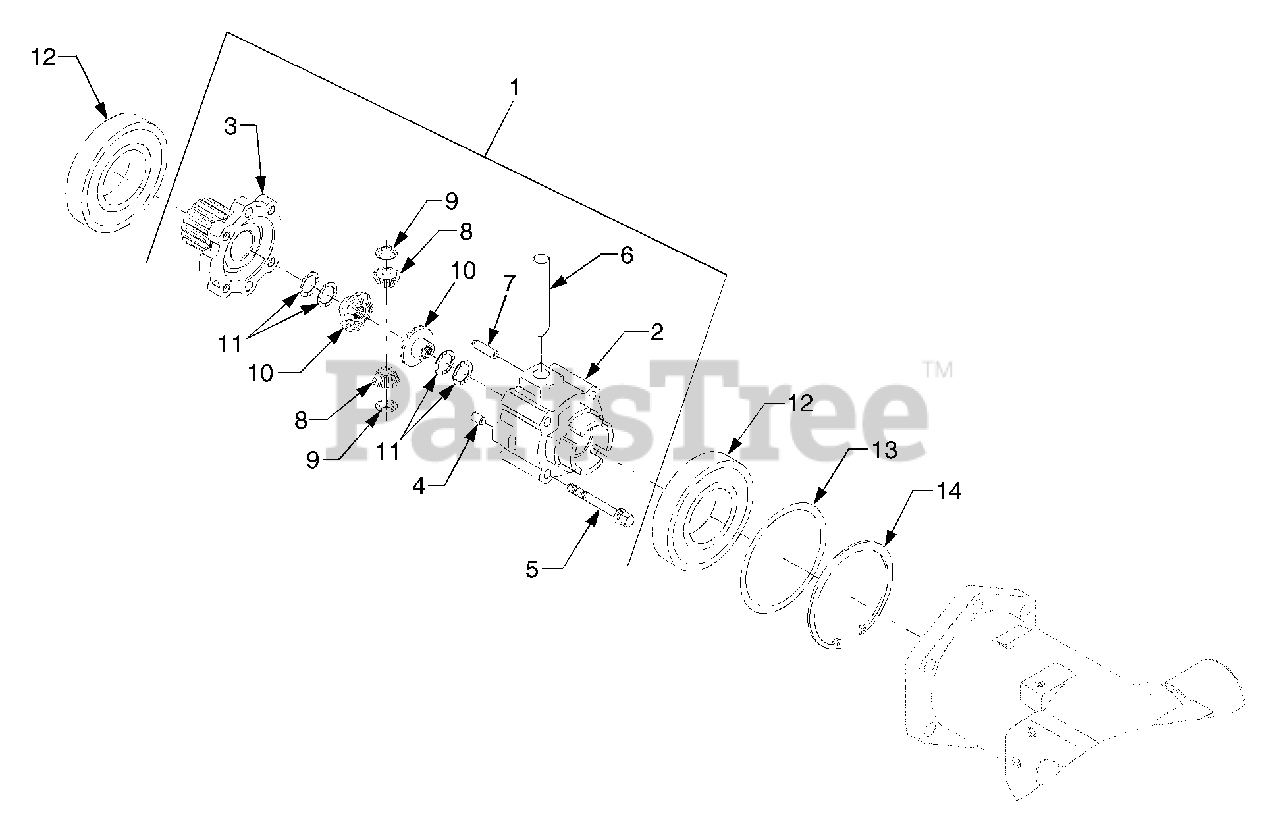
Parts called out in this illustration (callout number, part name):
1	Front Differential Ass'y
2	Case, Front Differential
3	Cover, Differential Case
4	Pin, Straight
6	Shaft, Differential Pinion
7	Pin, Straight
8	Pinion, Differential
9	Washer, Differential Side
10	Gear, Differential Side
12	Bearing, Ball
